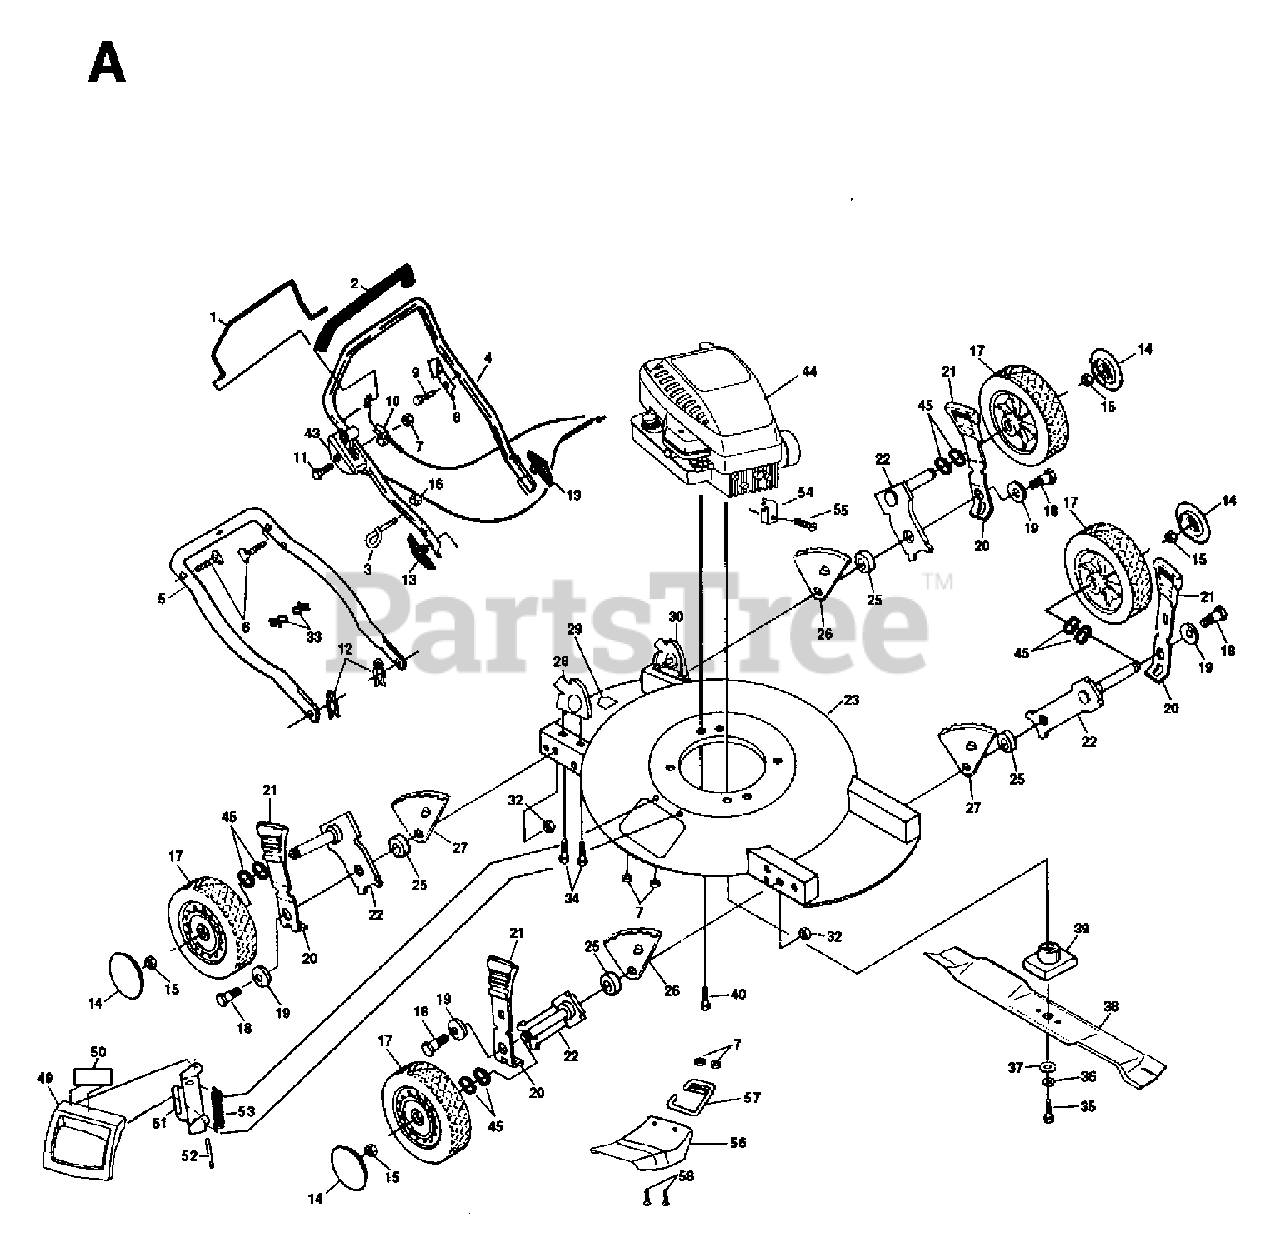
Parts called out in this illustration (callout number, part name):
1	CONTROL BAR/BLACK
2	HANDLE GRIP
3	ROPE GUIDE
4	UPPER HANDLE
6	HANDLE BOLT
7	NUT
8	BRACKET UPSTOP
9	TAPPING SCREW
10	CABLE
11	SCREW 1/4-20 X 2.12
12	HAIRPIN COTTER
13	HANDLE KNOB
15	HEX FLANGE LOCKNT
16	NUT
18	BOLT
19	BELLEVILLE WASHER
20	SELECTOR SPRING
21	SELECTOR KNOB
22	AXLE ARM
28	HDLE BRKT ASSY RH
29	DECAL MOWER CUT/FINGER
30	HDLE BRKT ASSY LH
32	LOCKNUT PM
33	CLIP CABLE SNAP
34	SELF-TAPPING SCREW 5/16-18X3/4
35	SCREW, HEX HD 3/8-24 X 1-3/8
36	LOCKWASHER
37	WASHER,HARDEN
38	BLADE.20.MULCH.(50DK,6020MD)
39	RP BLADE ADAPTOR
40	BOLT 3/8-16X1-1/8
43	THROTTLE CONTROL
45	WAVE WASHER
49	MULCHER DOOR
51	BRACKET PM
52	ROD.HINGE.COMBI-C
53	TORSION SPRING
55	SCREW.HEX.HEAD.WASHER.10-16
56	MULCHER DEFLECTOR
57	BRACKET.CHUTE.MTG
